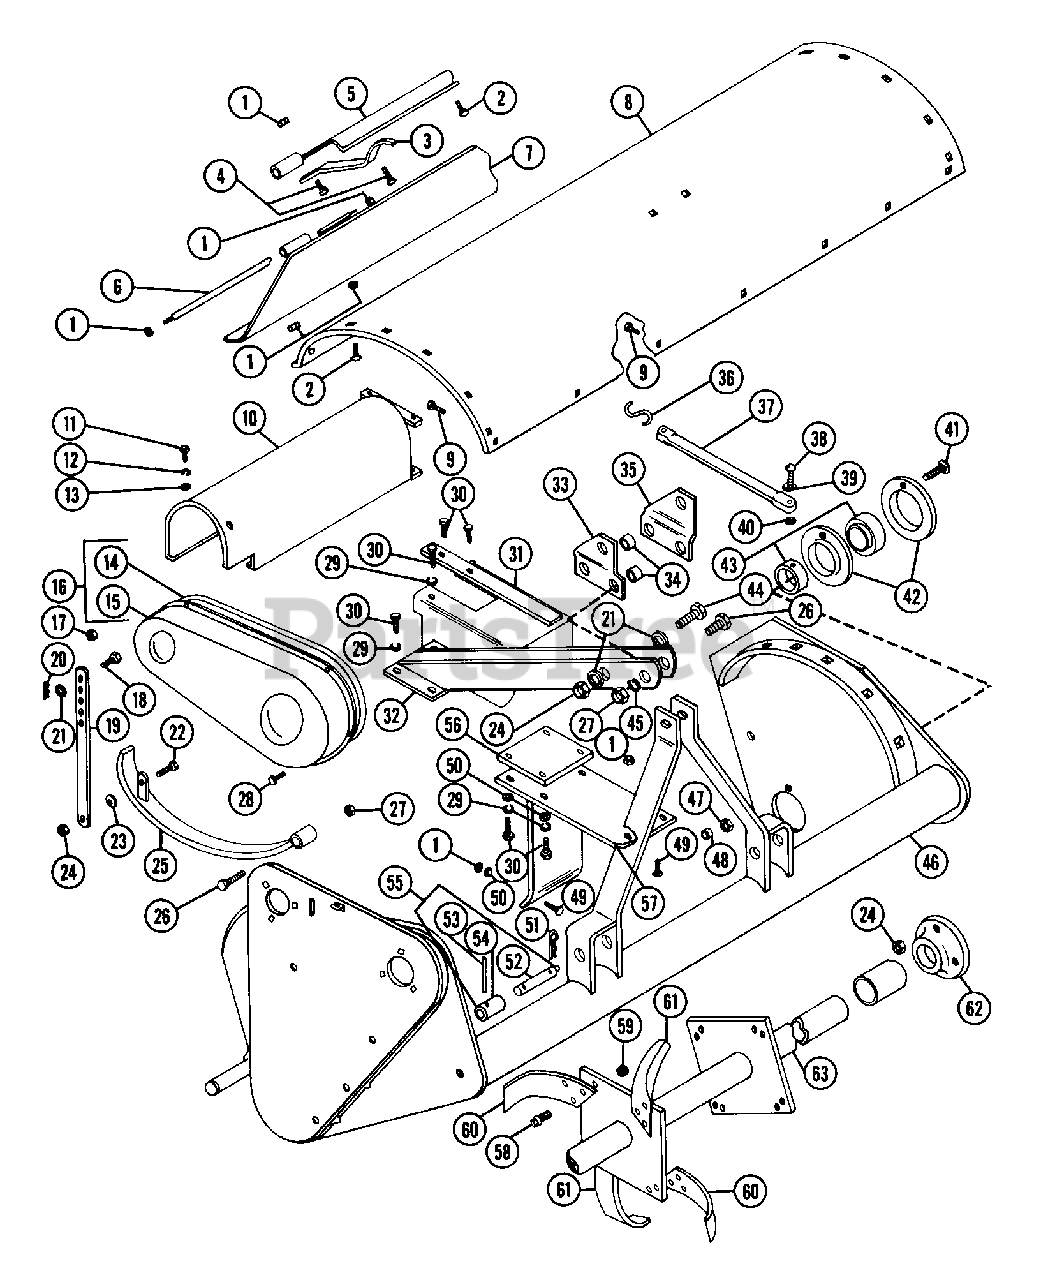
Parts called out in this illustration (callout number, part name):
1	NUT-LK TOP .375-16 GR C YWZC
2	BLT-RDHDSQNK .375-16X.75 GR5PL
4	BLT-RDHDSQNK .38-16X1.25 GR5PL
5	HINGE BRACKET
6	ROD-HINGE
7	LEVEL BLADE
8	SHROUD W/DECALS
9	SCR-TAP .312-18X.75 HWHPLDFGT
10	TUNNEL SHIELD
11	BLT-HEX .31-18X.50 PL GR2
12	WSHR-LK .313X.078 PL MED
13	WSHR-FL-STL.312X.734X.065PL
15	OUTER SHIELD
16	OUTER SHIELD ASSEMBLY
17	NUT-HEX .625-11
18	HEX BOLT-.62-11 X 1.50 SPECIAL
19	ADJUST STRAP
20	PIN-HAIR EXT .12X.31X2.37 PL
21	WSHR-FL-STL .505X1.000X.062
22	BLT-HEX .50-13X1.50 PL GR2
23	RUBBER WASHER
24	NUT-LK-CROWN .50-13 GR C PL
26	BLT-HEX .62-11X2.50 PL GR5
27	NUT-HEX .625-11
28	SCR-TAP .312-18X.50 HWH PL 1A
29	WSHR-LK .375X.115 HVY PL
30	BLT-HEX .38-16X1.25 PL GR5
31	PTO SHIELD
32	UPPER LINK
33	BRACKET RH
34	SPACER .630X.875X.625
35	BRACKET LH
37	RUBBER STRAP
38	SCR-MCH .25-20X1.25 SLRH PL
39	WSHR-FL-STL .250X.562X.049 PL
40	NUT-HEX .250-20 PL
41	BLT-RDHDSQNK .50-13X1.75 PL
42	FLANGETTE-4 HOLE
43	BRG-BALL 1.50X80MMX1.7
44	BLT-HEX .50-13X3.25 GR5
45	WSHR-LK .563X.141 MED PL
47	NUT .50-13 PL
48	SPACER .510X.750X.312
49	BLT-RDHDSQNK .38-16X1.0 GR5PL
50	WSHR-FL-STL .38X.875X.083 PL
51	PIN-HAIR INT .14X.4X2.75
53	PIN-ROLL .250X3.00
54	SPACER .635X.875X1.370
55	PIN ASSEMBLY
56	SPACER PLATE
57	GEAR BOX MOUNT
58	BLT-HEX .38-16X1.13 GR9
59	NUT-LK-FLG .375-16 PL
60	TINE RH
61	TINE LH
62	CAP-BEARING GUARD
63	TINE SHAFT
